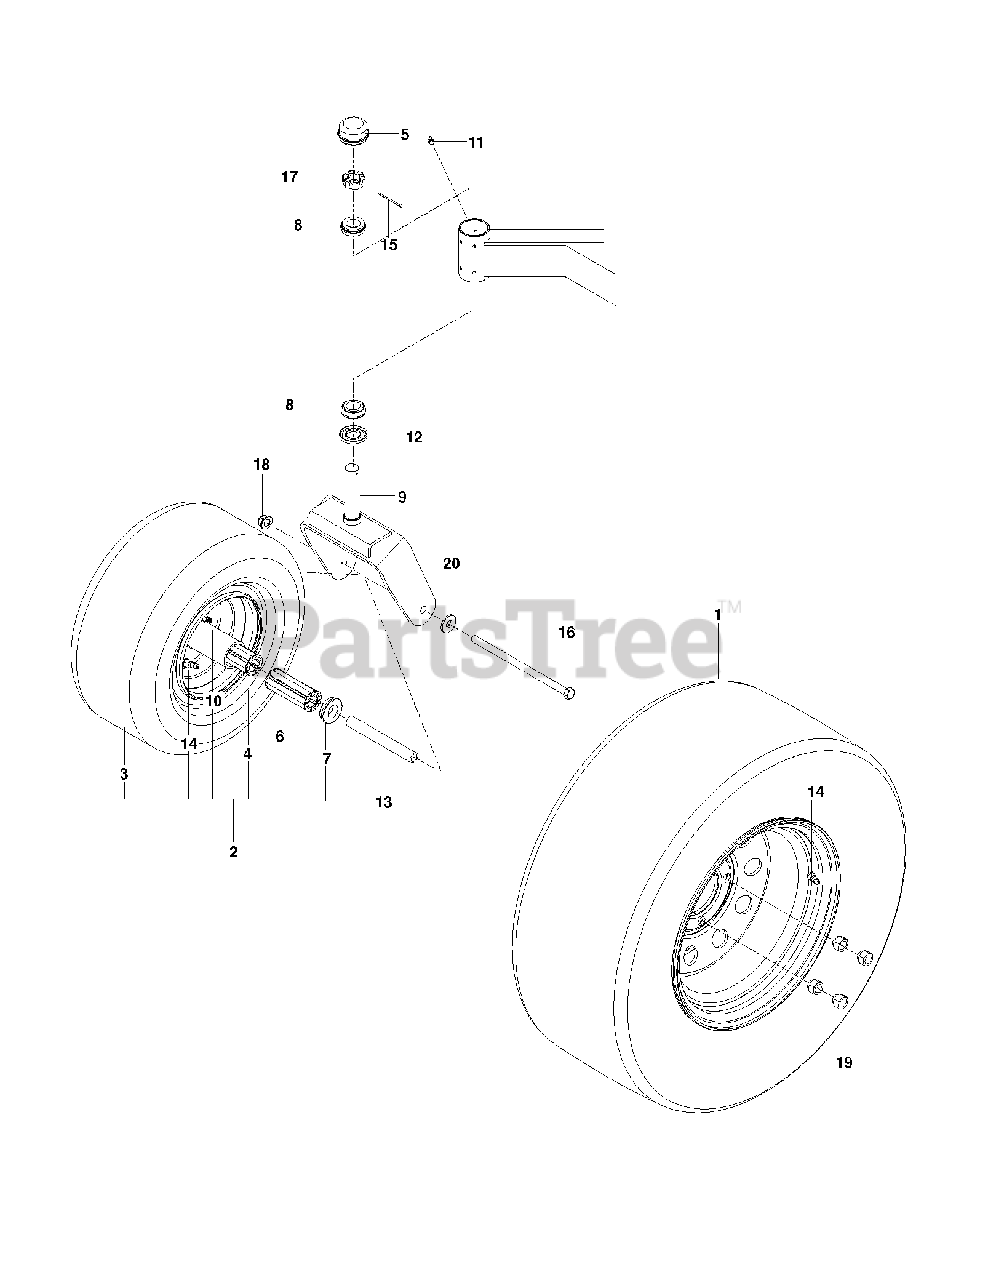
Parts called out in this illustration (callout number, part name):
1	WHEEL.ASSEM.22X10-10.SILVE.ZTR
2	TIRE.ASSEM.CASTER.13X6.5-6.SIL
3	TIRE.13X6.50-6.4.PLY
4	WHEEL.6X4.50.CASTER.SILVER
5	GREASE CAP
6	ROLLER BEARING-CAGED 3 1/4'
7	BEARING RETAINER
8	TAPERED ROLLER BRG
9	YOKE.CASTER.ORANGE
10	ZERK
13	SPACER, PIVOT
14	VALVE STEM TR-412
15	COTTER PIN 1/8 X 2
16	HEX SCREW 1/2-13 X 9.5 GR5
17	NUT 1"C HEX SLOTTED
18	NUT, 1/2-13 HEX FLG NYLOC ZD
19	LUG NUT 1/2F
20	WASH USS FLAT 1/2
